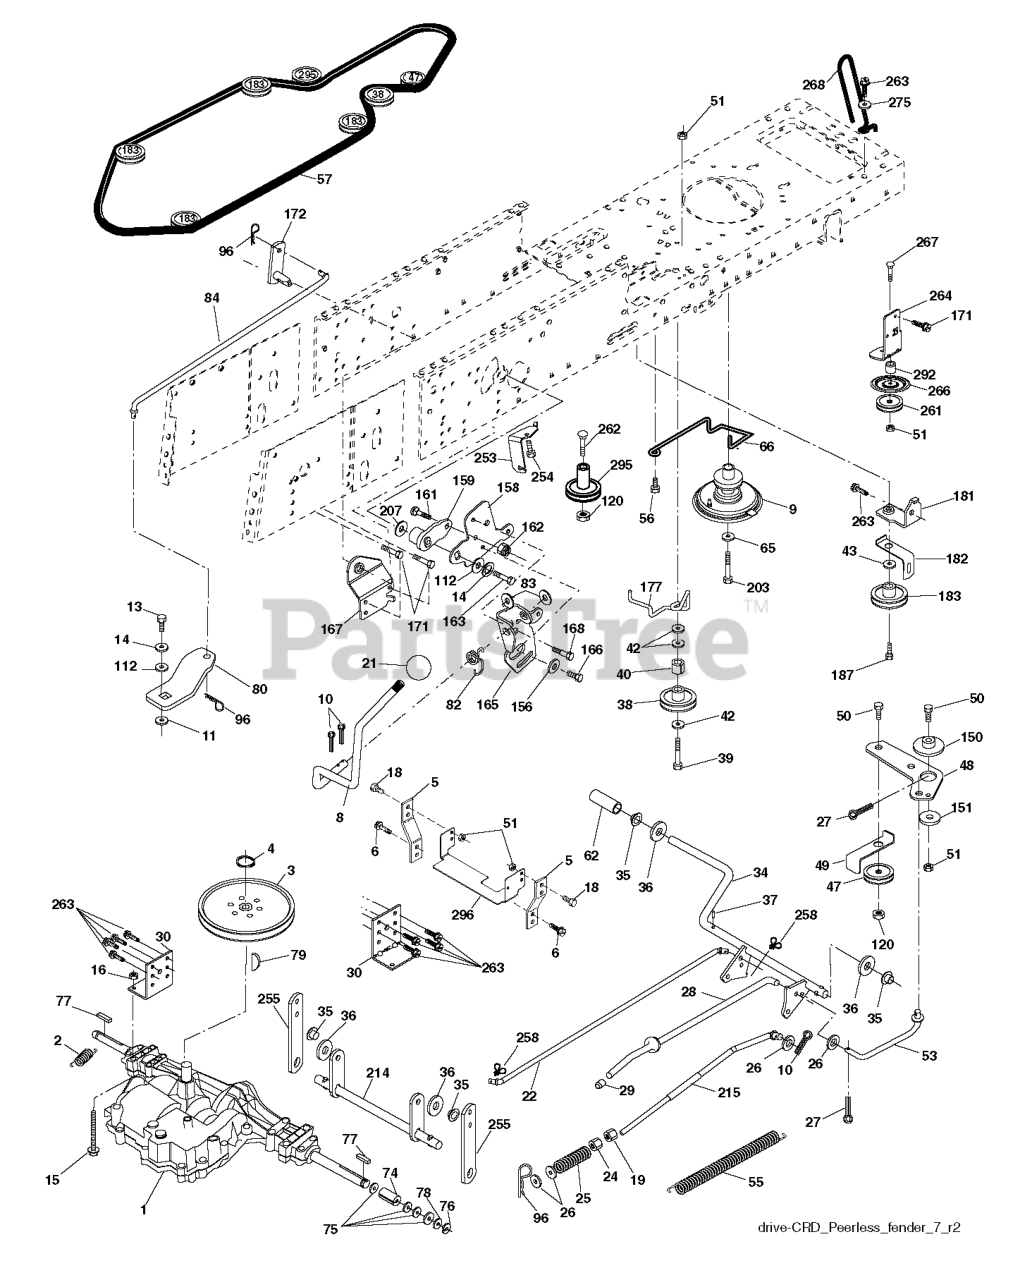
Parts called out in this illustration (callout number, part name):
2	SPRING,BRAKE RETURN
3	PULLEY
4	RETAINING RING LT
5	STRAP TORQUE
6	SCREW 5/16"
8	ROD SHIFT FENDER ADJUST LT
10	PIN COTTER
11	WASH-SHFT PLT LT
13	BOLT 1/4-28X3/4
14	LOCKWASHER
15	BOLT HEX 5/16-18 GR 5
16	NUT.71038.31-18.HEX.NYLOCK
19	NUT
21	KNOB T (1/2-HOLE)
22	ROD
24	NUT
25	SPRING ROD LT
26	WASHER
27	COTTER PIN
28	ROD, PARKING BRAKE
29	PLUNGER CAP
30	BRKT, MOUNT TRNSAXLE
34	SHAFT, FOOT PEDAL
35	BEARING.NYLON
37	DRIVE PIN
38	PULLEY.FLAT
42	WASHER
47	IDLER PULLEY
48	BELLCRANK, CLUTCH
49	RETAIN BELT
50	BOLT.3/8-16X1.50
53	LINK.CLUTCH.7.66.2005
55	SPRING, RETURN LT
56	SCREW.3/8-16
57	V-BELT.KEV.111"
62	PEDAL COVER T
65	LOCKWASHER
66	KEEPER BELT ENGINE
74	SPACER AXLE
77	SQUARE KEY
79	KEY STD (1373) DANA
82	SHIFT SPRING
83	WASHER
96	RETAINER M
120	NUT LOCK FLG 3/8-16 UNC
150	BUSHING.BELLCRANK.GRD.DR
151	WASHER 12/32X2X10GA
156	WASHER.SRRTD.5/16
158	BRACKET
159	RB HUB.SHIFT
161	BOLT
162	NUT.CROWNLOCK.1/4
165	RP BRACKET
166	CAPSCREW.HXHD.FLG.5/16-18X.625
167	BRACKET.SUPT.SHIFT.CRD
168	BOLT.SHOULDER.5/16-18X
172	SHAFT
181	BRACKET
182	BELT GUIDE
183	PULLEY.V-IDLER.GRND.DR
187	BOLT.5/16-18X1.25
203	BOLT.HEX.7/16-20 X 5
207	WASHER NYL
214	LEVER
254	SCREW 3/8-16X1
255	SHAFT
258	CLIP RETAINER
261	FLAT IDLER PULLEY
263	SCREW, 3/8-16X3/4
266	PROTECTOR
268	GUARD MUFFLER
275	WASHER
295	PULLEY IDLER COMPOSITE
